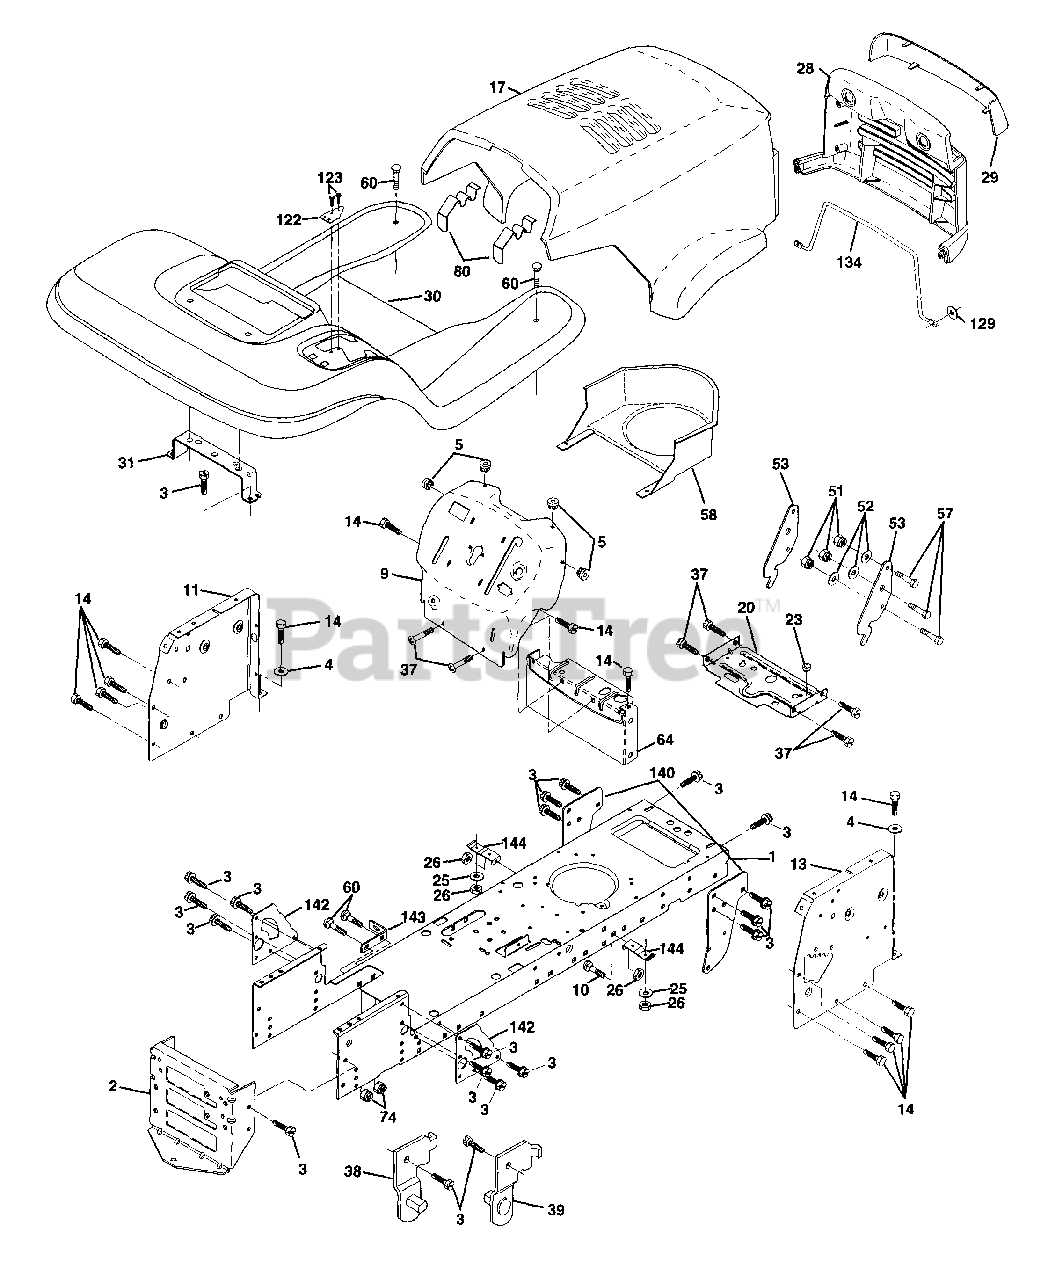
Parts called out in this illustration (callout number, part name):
1	Chassis Weldment
2	Drawbar,
3	Screw
4	Washer 13/32 x 3/4 x 16 Ga.
5	Bumper Hood/Dash
9	Dash P/L M, N/AMM N/HM Grey
10	Bolt Carriage 3/8-16 x 1
11	Panel Dash Lh
13	Panel Dash Rh
14	Screw Thdrol 3/8-16x1/2 Ty-tt
17	Hood LT/PL Husqvarna
20	Plate Mtg Battery Fuel Tank Fr
25	Washer 13/32 X 13/16 X 12 Ga
26	Nut Lock Hex W/Ins 3/8-16 Unc
28	Grille LT/PL Husqvarna
29	Lens LT/PL Husqvarna
30	Fender Footrest STLT Pnt
31	Bracket Support Fender
37	Screw Thdrol 6/16-18 x 1/2 TYT
38	Bracket, Asm. Pivot, L.H., Mower Rear
39	Bracket, Asm. Pivot, R.H., Mower Rear
51	Nut Lock Hex W/lns 1/4-20
52	Washer 9/32 x 7/8 x 16 Ga.
53	Bracket Pnt. Pick off LT/PL Husqvarna
57	Bolt Hex 1/4-20 x 3/4
58	Air Duct Engine P/L
60	Bolt Rdhd Sqnk 3/8-16unc x 3/4
64	Dash Lower STLT
74	Nut Crownlock 3/8-16 UNC
80	Latch Hood Plm Husqvarna
129	Washer 9/32 x 5/8 x 16 Ga.
134	Rod Support Hood ET/PL Husq.
140	Bracket Chassis Front 7 Ga.
142	Plate Reinforcement STl T
143	Bracket Swaybar Chassis
144	Bracket Pnt Footrest STLT
146	Screw Torx Hd Thd 5/16-18 UN-2A
